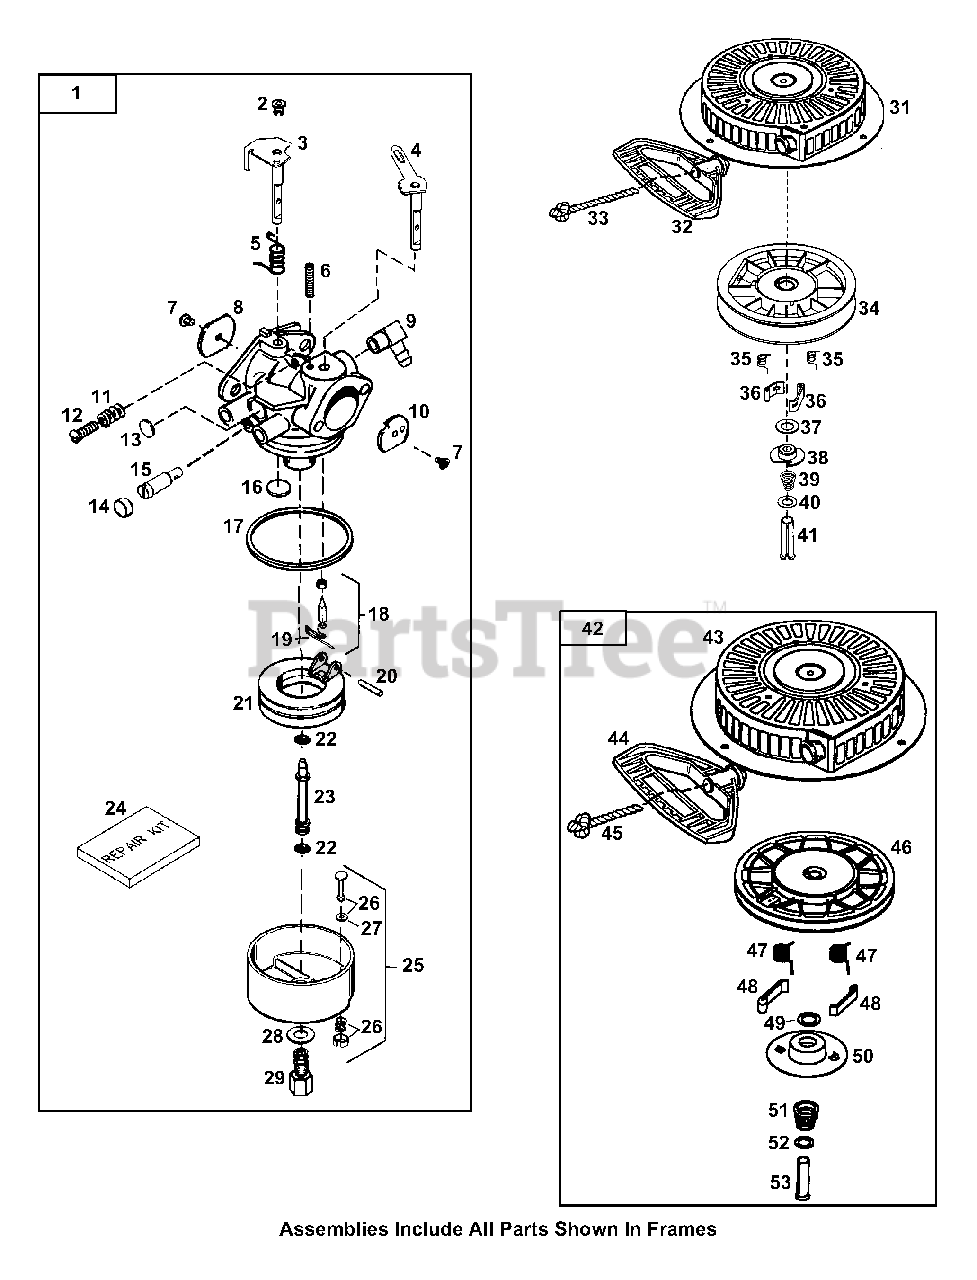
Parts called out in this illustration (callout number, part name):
1	Carburetor Assembly
2	Throttle Link Bushing
3	Throttle Shaft & Lever Assembly
4	Choke Shaft & Lever Assembly
5	Throttle Return Spring
6	Choke Positioning Spring
7	Shutter Screw
8	Throttle Shutter
9	Fuel Fitting
10	Choke Shutter
11	Tension Spring
12	Throttle Crack Screw/Idle Speed Screw
13	Welch Plug, Idle Mixture Well
14	Idle Restrictor Screw Cap
15	Idle Restrictor Screw
16	Welch Plug, Atmospheric Vent
17	Float Bowl O- Ring
18	Inlet Needle, Seat & Clip
19	Spring Clip
20	Float Shaft
21	Float (Plastic)
22	O- Ring, Main Nozzle Tube
23	Main Nozzle Tube
24	Repair kit
25	Float Bowl Assembly
26	Bowl Drain Assembly
27	Drain Plunger Gasket
28	Bowl Nut Washer
29	High Speed Bowl Nut
31	Starter Housing Assembly
32	Mitten Grip Handle
33	Starter Rope (Length 98" x 9/64" dia.)
34	Pulley & Rewind Spring Assembly
35	Dog Spring
36	Starter Dog
39	Brake Spring
41	Spring Pin
42	Rewind Starter Ass'y
43	Starter Housing Ass'y
44	Mitten Grip Starter Handle
45	Starter Rope (98")
46	Pulley & Rewind Spring Ass'y
47	Dog Spring
48	Starter Dog
51	Brake Spring
53	Spring Pin
